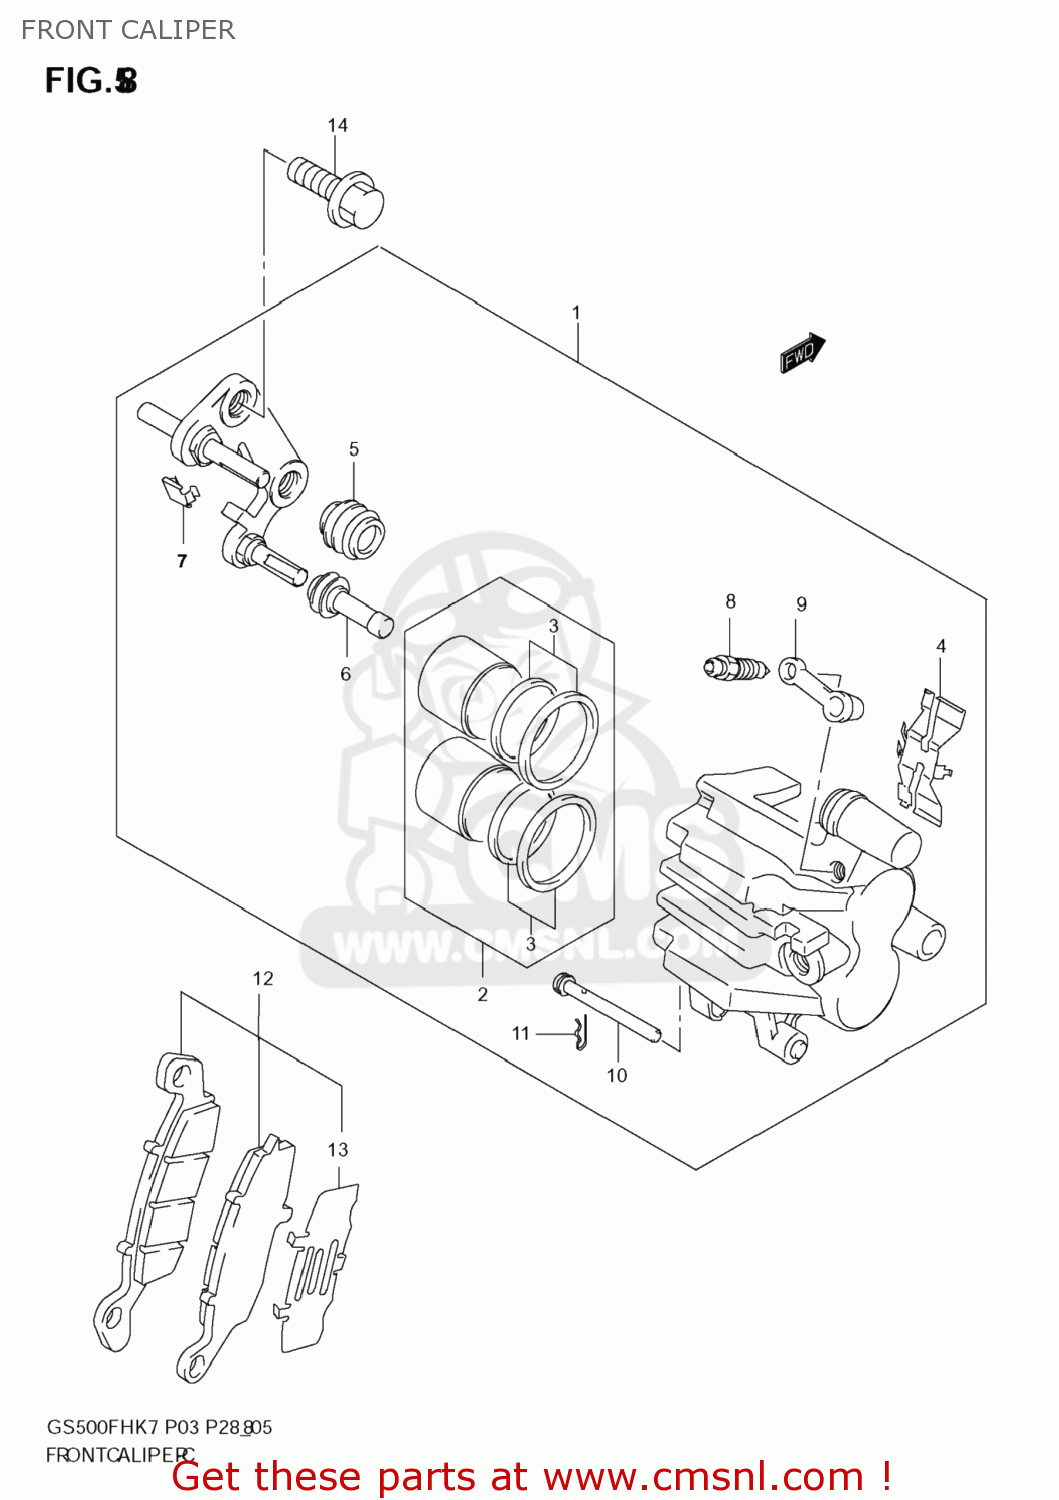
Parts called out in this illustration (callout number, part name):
1	CALIPER ASSY,F
2	PISTON SET
3	SEAL SET PISTO
4	SPRING
5	BOOT
6	INSULATOR
7	GUIDE
8	BLEEDER
9	CAP
10	PIN
11	CLIP
12	PAD & SHIM SET (NAS)
13	SHIM,PAD
14	BOLT
